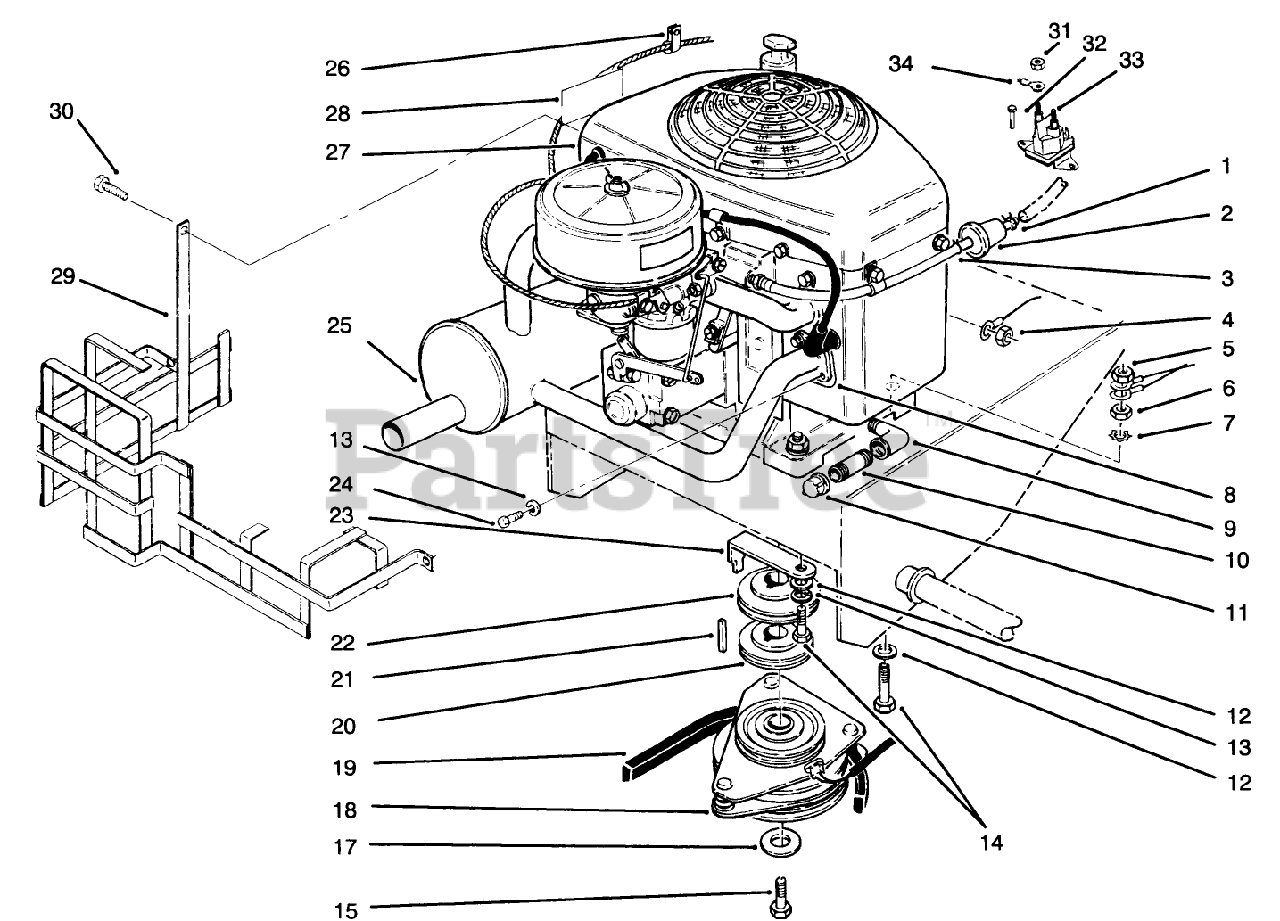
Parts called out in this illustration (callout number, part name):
1	CLAMP-HOSE
2	Fuel-Filter
3	HOSE-FUEL
4	NUT-KEPS
5	NUT-KEPS
6	NUT-LOCK, CONE
7	WASHER-LOCK
8	EXHAUST GASKET F/W ENG.
9	ELBOW-STREET, 90 DEG
10	NIPPLE
11	CAP-PIPE
12	WASHER-PLAIN
13	WASHER-LOCK
14	SCREW-HH
15	SCREW-HH
17	WASHER
18	CLUTCH/BRAKE
19	BELT V
20	SHEAVE-LOWER HALF
21	KEY-SQUARE
22	SHEAVE-UPPER HALF
23	Retainer-Clutch
24	SCREW-HSH
25	MUFFLER
26	CLAMP-R
28	DECAL-SURFACE, HOT
29	WA - MUFFLER GUARD B
30	Screw-Hex. Hd.(Engine)
31	NUT-KEPS
32	SCREW
33	Solenoid
34	WIRE-SOLENOID/STARTER
